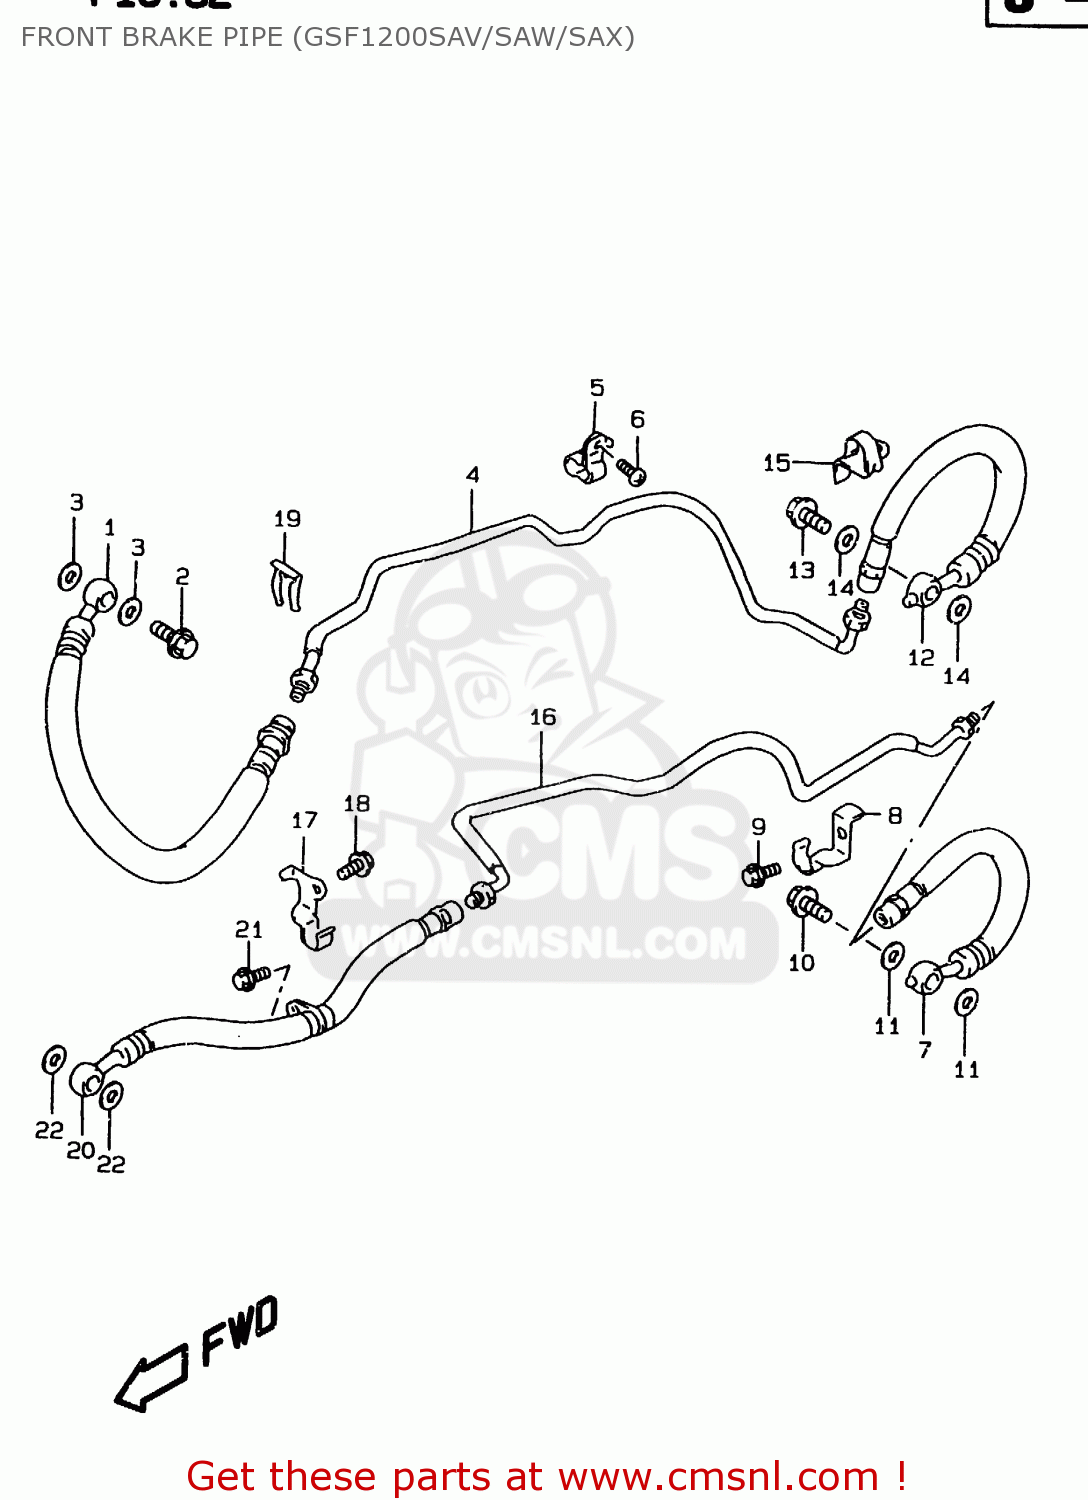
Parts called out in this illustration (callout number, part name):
1	HOSE COMP,FRONT BRAKE
2	BOLT UNION
3	WASHER(10X15X1.5)
4	PIPE,FR BRAKE NO.1
5	CLAMP,FR BRAKE PIPE
6	SCREW
7	HOSE,FR BRAKE HU OUT
8	CLAMP,FR BRAKE HOSE HU OUT
9	BOLT
10	BOLT UNION
11	WASHER(10X15X1.5)
12	HOSE,FR BRAKE HU IN
13	BOLT UNION
14	WASHER(10X15X1.5)
15	CLAMP,FR BRAKE HOSE HU IN
16	PIPE,FR BRAKE NO.2
17	CLAMP,FR BRAKE HOSE JOINT
18	BOLT
19	E RING
20	HOSE,FR BRAKE JOINT
21	BOLT
22	WASHER(10X15X1.5)
